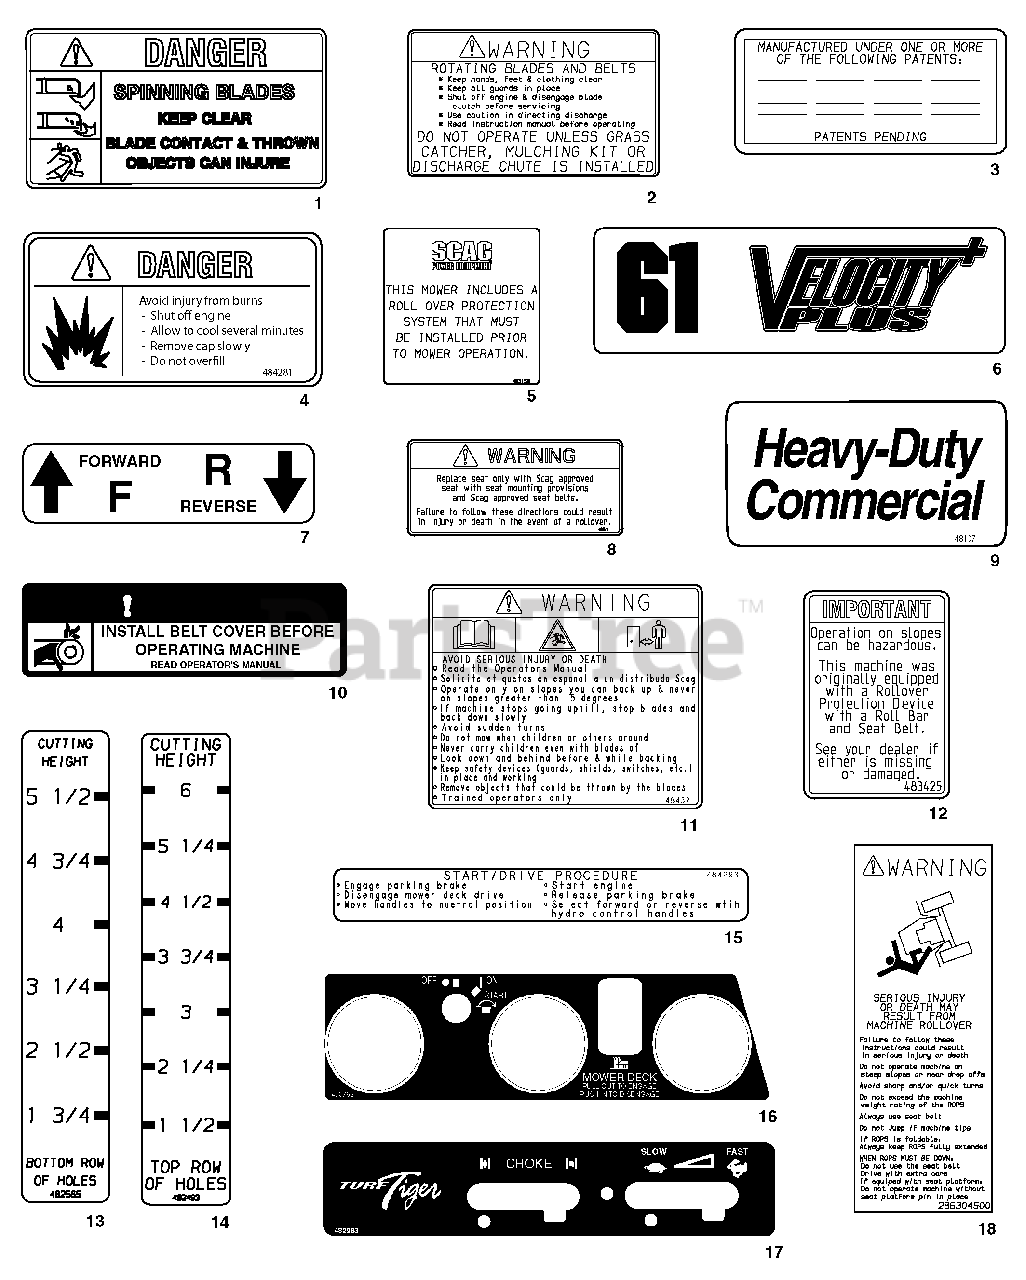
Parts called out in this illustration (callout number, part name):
1	Decal, Danger-Spinning Blades
2	Decal, Warning-Rotating Blades
3	Decal, Patents
4	Decal, Fuel Tank
5	Decal, ROPS
6	Decal, 61" Velocity Plus
6	Decal, 72 Velocity Plus
7	Decal, Traction Control
8	Decal, Seat Replacement
9	Decal, Heavy Duty Commercial
10	Decal, Belt Cover
11	Decal, Warning
12	Decal, ROPS
13	Decal, Cutting Height - Lower
14	Decal, Cutting Height - Upper
15	Decal, Start/Drive Procedure
16	Decal, Instrument Panel - Upper
17	Decal, Instrument Panel - Lower
18	Decal, ROPS Warning
